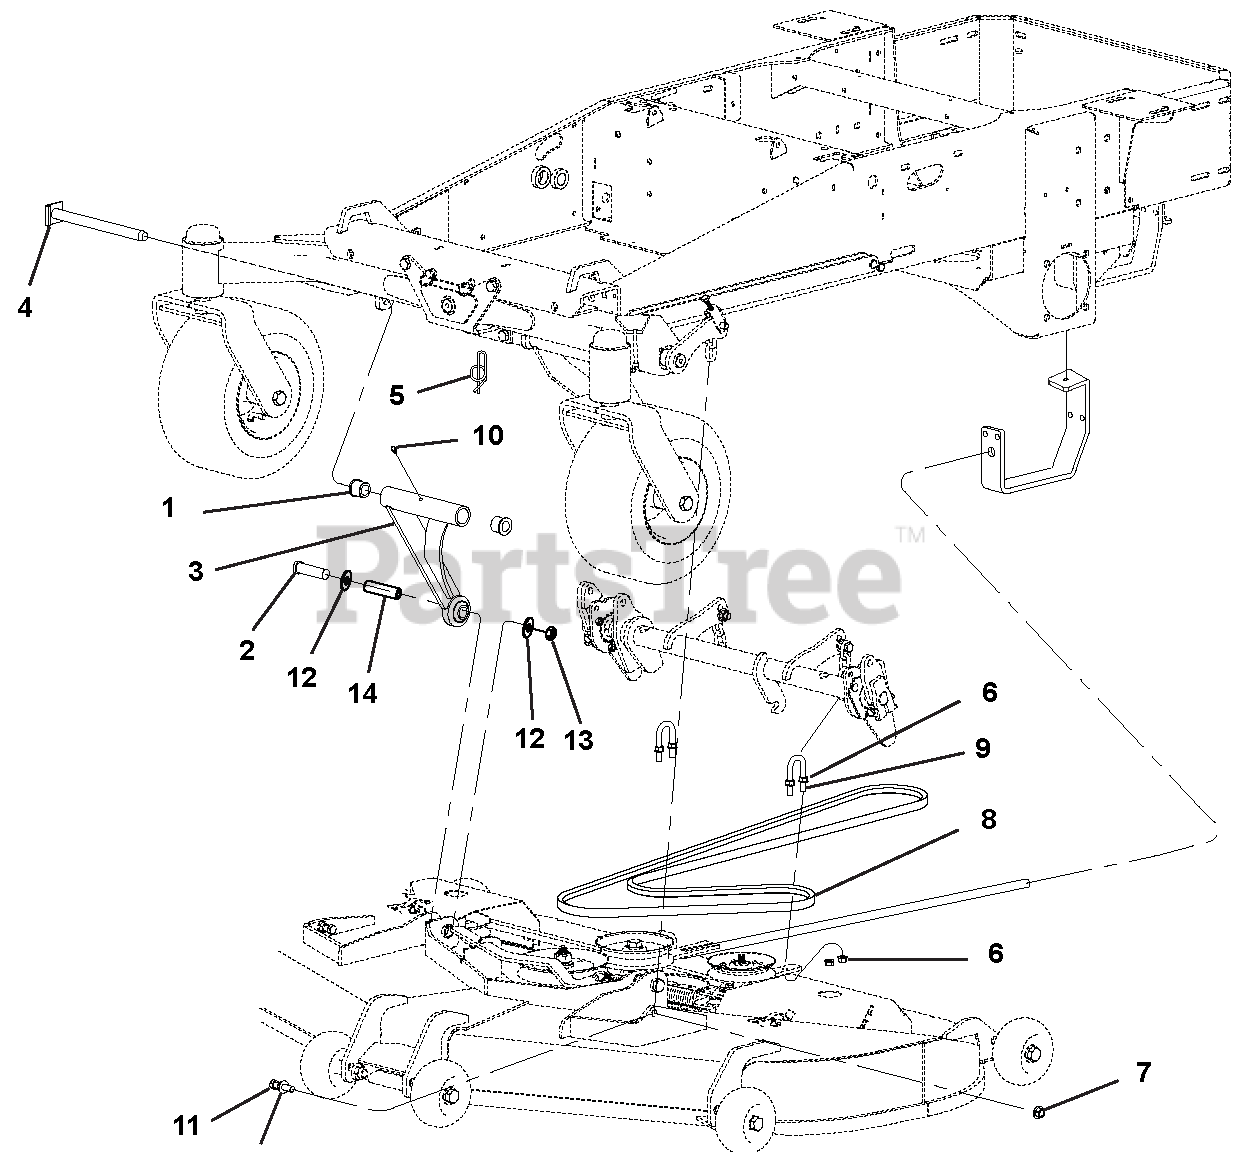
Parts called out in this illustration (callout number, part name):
1	BRG, FLG .750X1.13X1.00
2	@BLT-HEX .50-13X3.50 GR5 YWZC
3	WLDT, DECK PULL 11.5
4	PIN, PVT .750X9.75X9.20 XDRL U
5	RING, RUE .750 X .080 X 2.081
6	@NUT-SPNLK-FLG .375-16 YWZC
7	NUT-FLANGED WHIZ .438-14 YWZC
8	BELT, HB 114.9 EL AMD
9	U-BOLT, RD 1.00X3.00X3/8-16 Y
10	FTG, 1/4-28 STRGT GREASE ZERK
11	@BLT-HEX .44-14X1.75 GR5 YWZC
12	@WSHR-FL-STL.563X1.38X.109YWZC
13	NUT-LK-CONE .50-13 GR C YWZC
14	TUBE, RD .750 X.125W X 2.469
